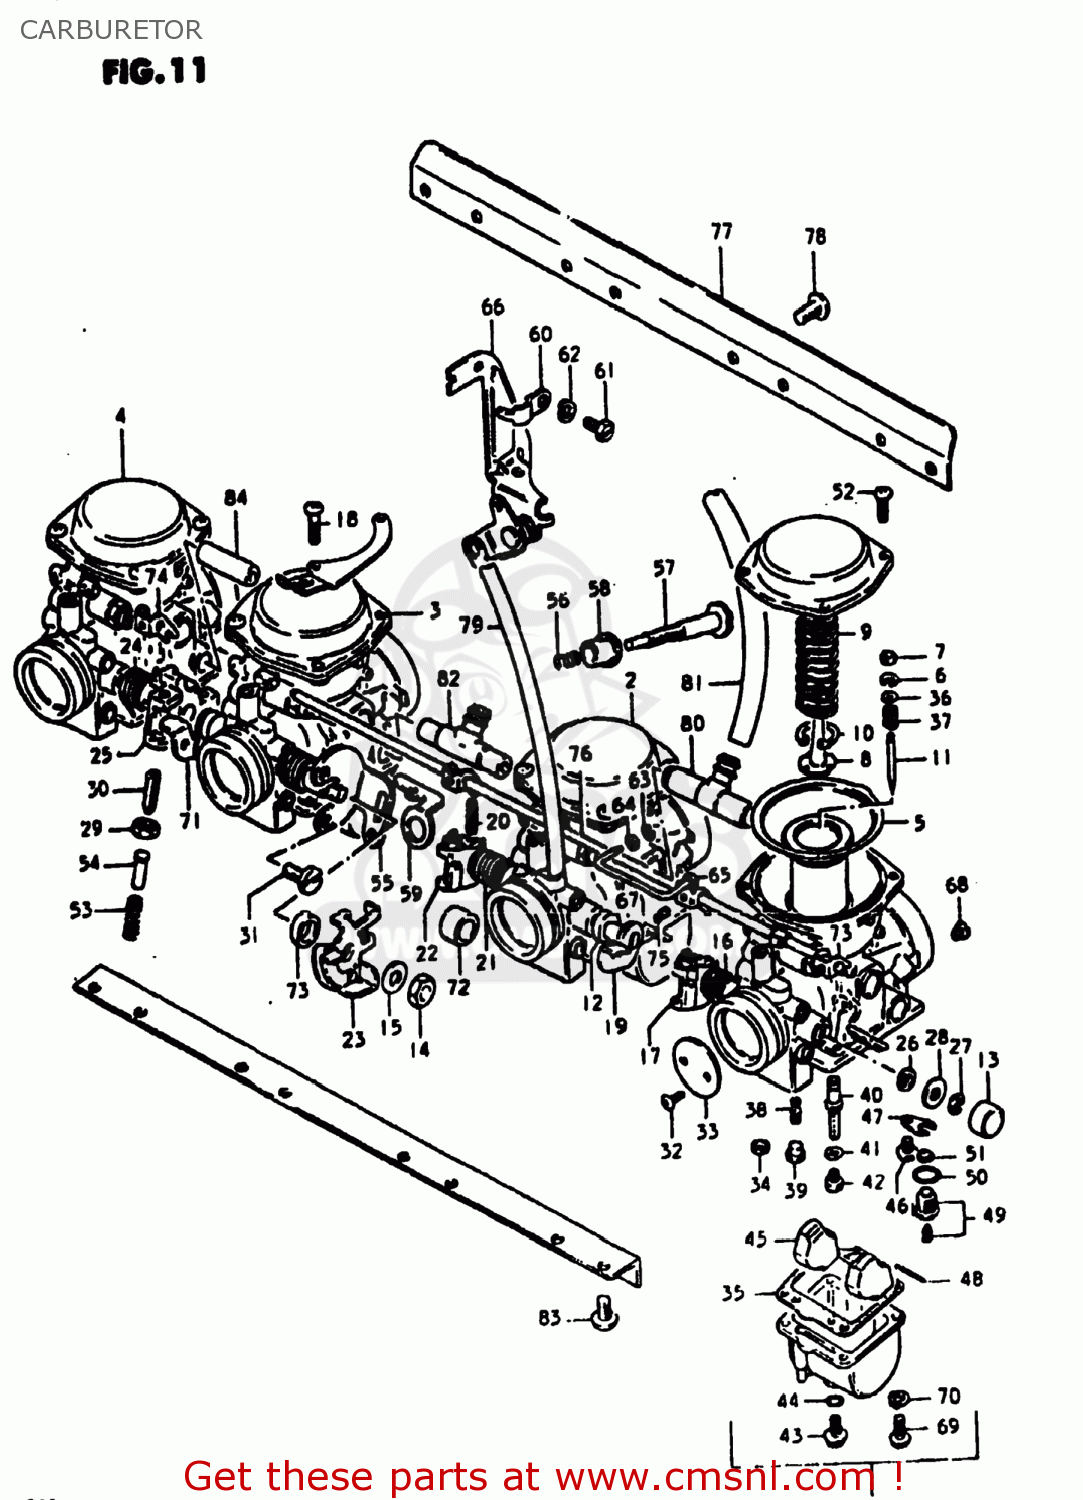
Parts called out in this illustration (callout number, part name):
1	CARBURETOR ASSEMBLY
2	CARBURETOR ASSEMBLY
3	CARBURETOR ASSEMBLY
4	CARBURETOR ASSEMBLY
5	DIAPHRAGM ASSEMBLY
6	CLIP,NEEDLE
7	RING
8	HOLDER,GUIDE
9	SPRING
10	E RING
11	NEEDLE JET
12	GASKET
13	CAP
14	NUT
15	WASHER
16	SPRING,THROTTLE SHAFT
17	SHAFT,THROTTLE
18	SCREW
19	SHAFT,THROTTLE
20	PIN,THROTTLE SHAFT
21	SPRING,THROTTLE SHAFT
22	LEVER,THROTTLE SHAFT
23	LEVER ASSEMBLY,THROTTLE
24	SPRING,THROTTLE SHAFT
25	SHAFT,THROTTLE
26	SEAL
27	E RING
28	GASKET,THROTTLE SHAFT (NAS)
29	NUT
30	SCREW
31	SCREW
32	SCREW
33	VALVE,THROTTLE (BUTTERFLY)
34	GASKET (NAS)
35	GASKET,FLOAT CHAMBER (NAS)
36	WASHER
37	SPRING
38	JET,PILOT
39	PLUG,NEEDLE JET
40	JET,NEEDLE
41	WASHER,NEEDLE NOZZLE
42	JET,MAIN(107.5)
43	PLUG,DRAIN
44	GASKET (NAS)
45	FLOAT
46	SCREW
47	PLATE
48	PIN,FLOAT
49	VALVE ASSEMBLY,NEEDLE
50	O RING
51	FILTER
52	SCREW
53	SPRING,THROTTLE SCREW
54	PIN,THROTTLE LEVER
55	BRACKET,THROTTLE ADJUST
56	SPRING
57	SCREW
58	BUSH
59	BRACKET,THROTTLE ADJUST
60	BRACKET,STARTER
61	BOLT
62	LOCK WASHER
63	CAP,LEVER
64	SEAT,SPRING
65	LEVER ASSY
66	BRACKET
67	ROD,STARTER LEVER
68	JET,AIR(190)
69	SCREW
70	LOCK WASHER
71	SHAFT,THROTTLE
72	RING
73	RING
74	LEVER
75	SCREW
76	SHAFT,STARTER
77	BRACKET
78	SCREW
79	HOSE
80	NIPPLE
81	HOSE
82	NIPPLE
83	SCREW 6X12
84	NIPPLE
